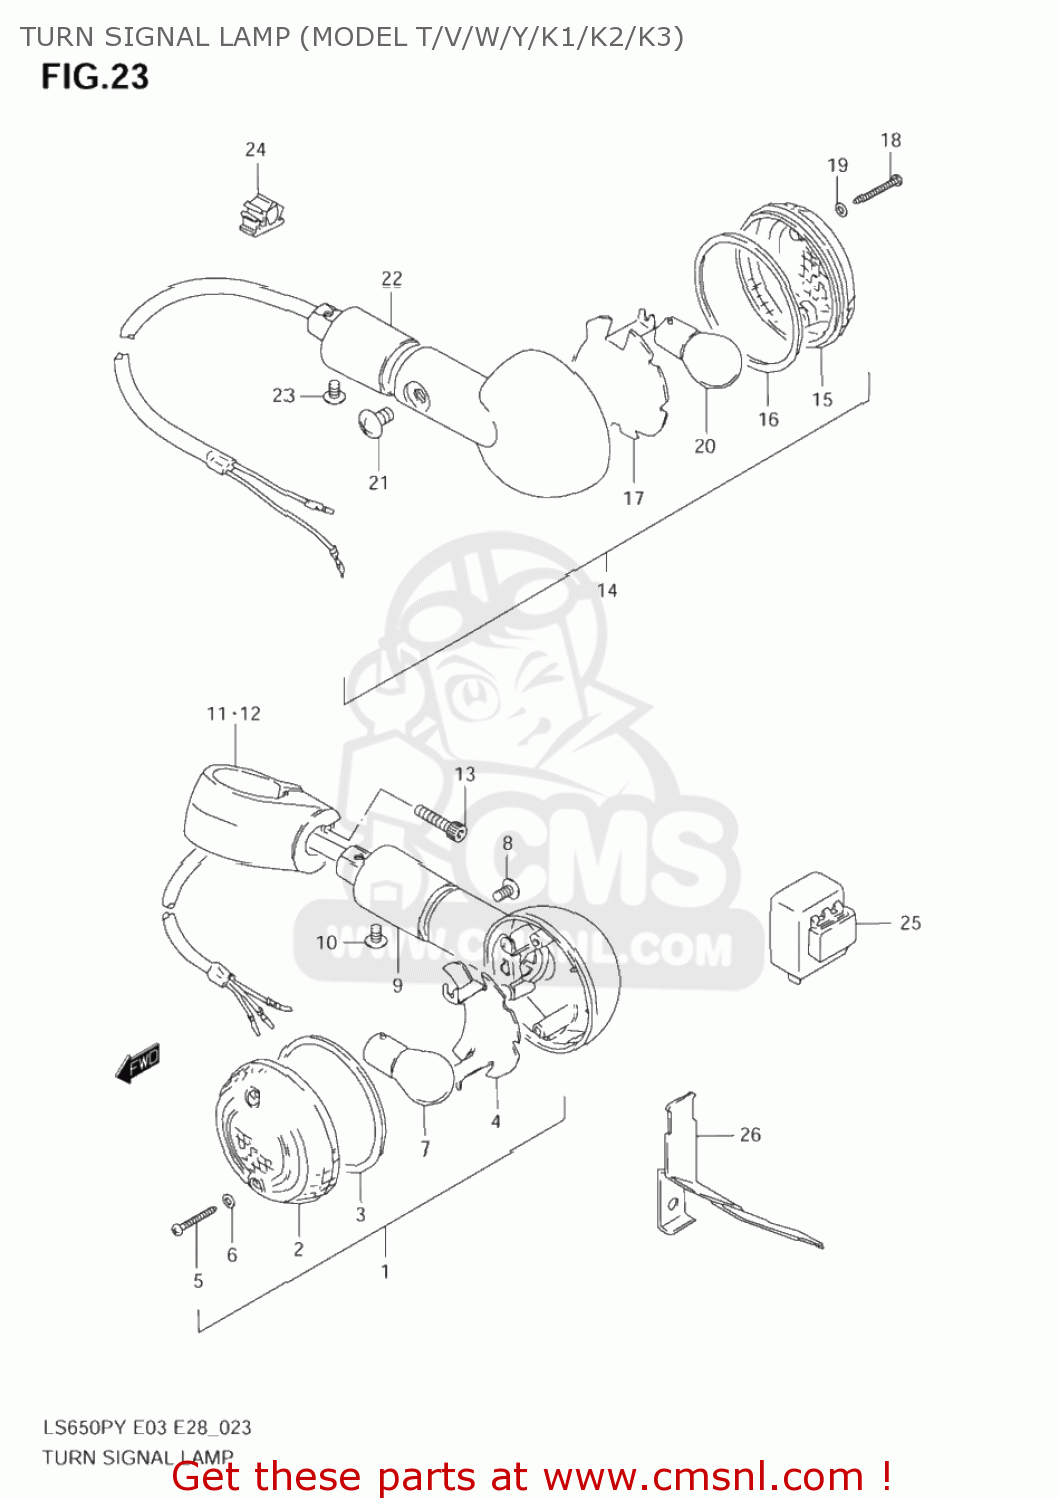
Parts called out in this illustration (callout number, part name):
1	LAMP ASSY,FR TURN SIGNAL
2	LENS
3	GASKET (NAS)
4	REFRECTOR
5	SCREW
6	GASKET (NAS)
7	BULB(12V21/5W,BF141-49642A)
8	SCREW
9	STAY,TURNSIGNAL LAMP
10	SCREW
11	BRACKET,FR TURNSIGNAL LAMP,R
12	BRACKET,FR TURNSIGNAL LAMP,L
13	BOLT
14	LAMP ASSY,FR TURN SIGNAL
15	LENS
16	GASKET (NAS)
17	REFRECTOR
18	SCREW
19	GASKET (NAS)
20	BULB(12V21W)
21	SCREW
22	STAY,TURNSIGNAL LAMP
23	SCREW
24	CLAMP
25	RELAY ASSY
26	BRACKET,TURNSIGNAL RELAY
